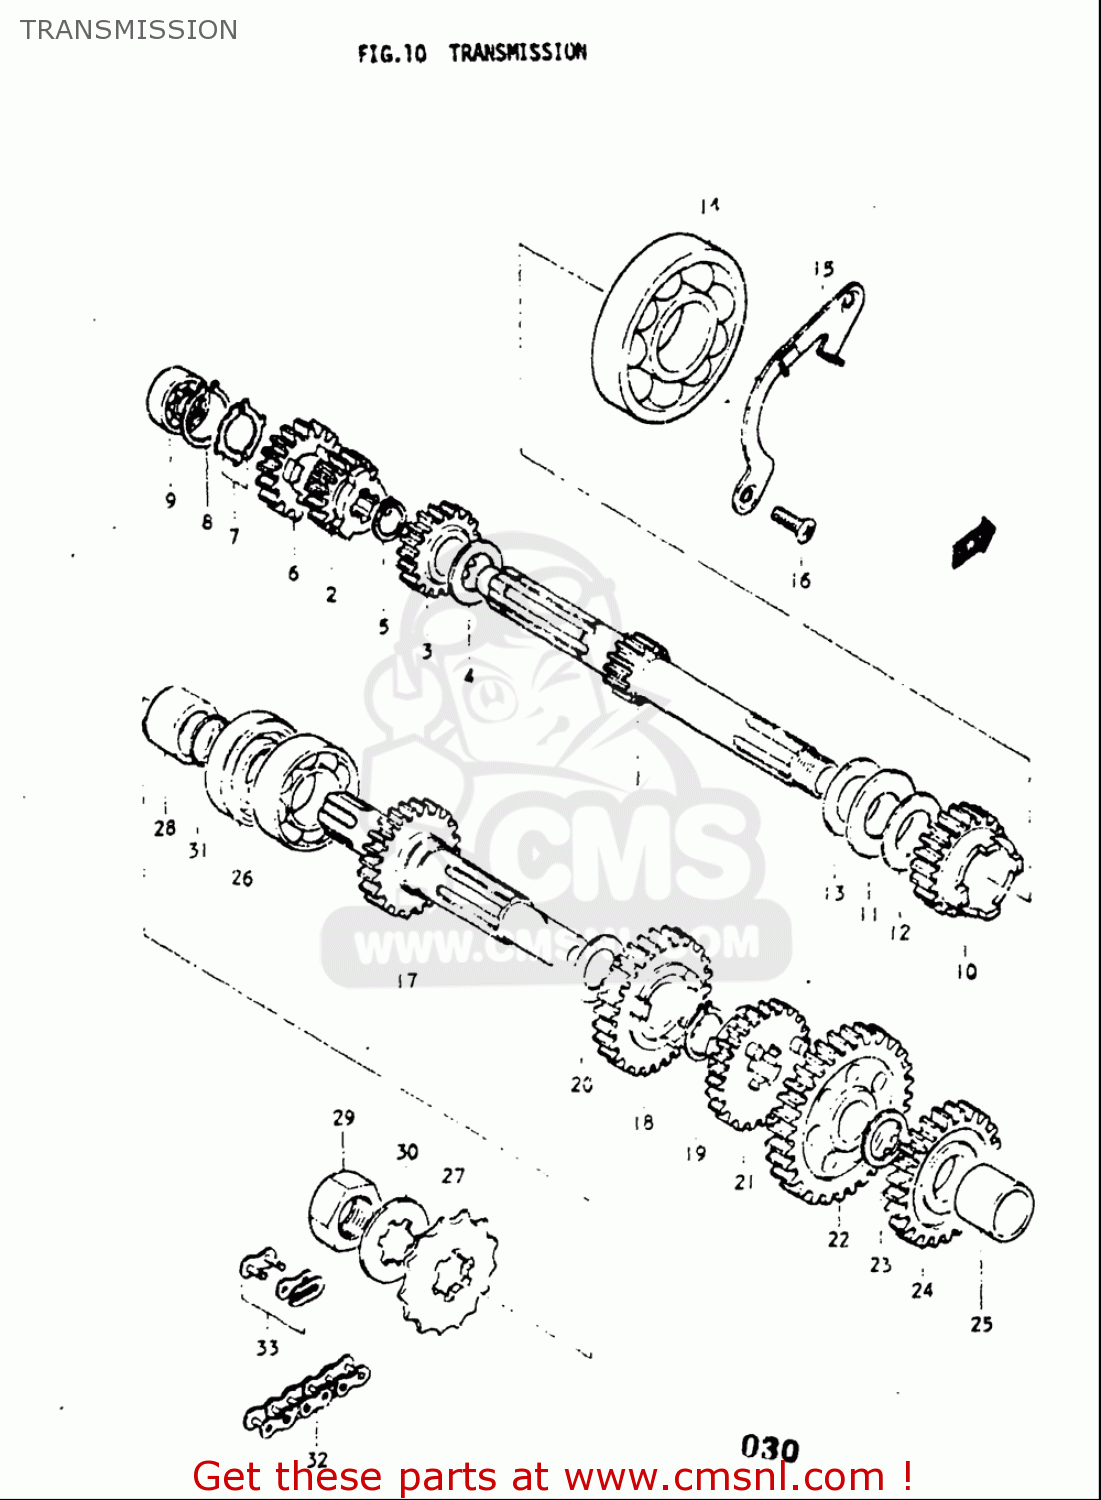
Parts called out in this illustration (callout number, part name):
2	GEAR,2ND DRIVE
3	GEAR,3RD DRIVE
4	WASHER
5	CIRCLIP
6	GEAR,4TH DRIVE(NT:20)
8	RING,SNAP
9	BEARING(12X28X8)
10	GEAR,KICK STARTER DRIVEN
11	BEARING(21X32X2.85)
13	WASHER(21X30X0.8)
14	BEARING(30X62X10)
16	SCREW
18	GEAR,2ND DRIVEN
19	CIRCLIP
20	SHIM(20X28X1)
21	GEAR,3RD DRIVEN
22	GEAR,1ST DRIVEN
23	WASHER
24	GEAR,KICK STARTER IDLE
25	BUSH
26	SEAL,OIL(25X40X9)
27	SPROCKET,ENGINE(NT:14)
29	NUT
30	WASHER,LOCK
31	O RING(D:1,ID:19.5)
32	CHAIN,DRIVE(DID428HG,134L)
